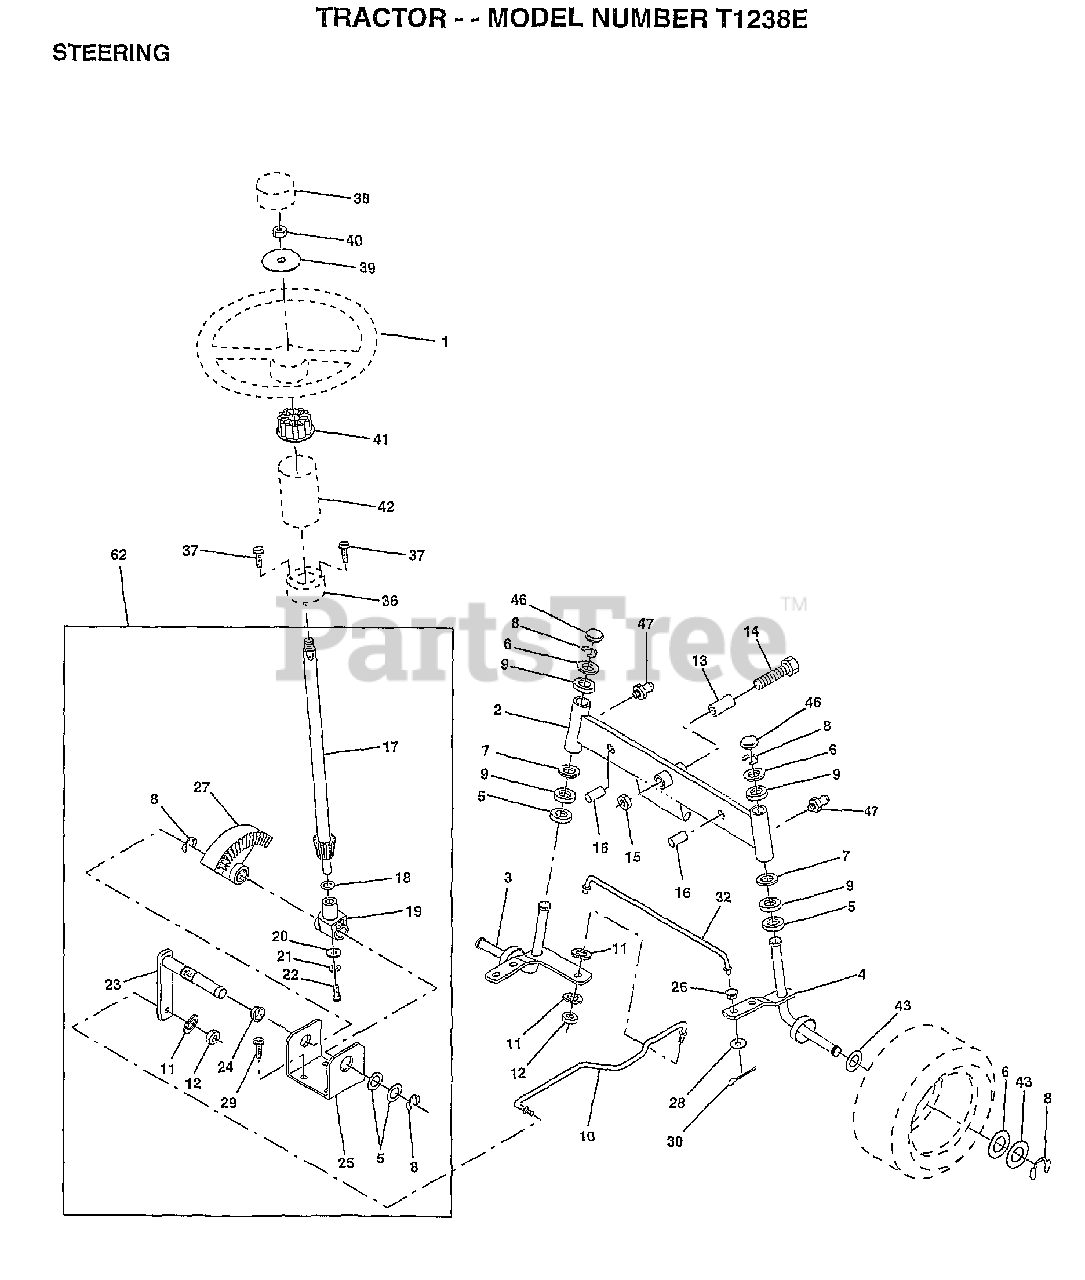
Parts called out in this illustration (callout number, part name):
2	AXLE ASM FRONT
3	SPINDLE LH
4	SPINDLE RH
5	WASHER .T
6	WASHER
7	WASHER
8	RING
9	COL. SRTG. BEAR.
11	LOCKWASHER
13	BEARING
14	BOLT HEX 5/8-11
15	"NUT-LOC,FLANGE LT"
16	AXLE PIN
17	SHAFT ASM
18	THRUST WASHER
19	SUPPORT.SHAFT
21	LOCKWASHER
22	SCREW.SCKTHD.CAP
24	NYLINER T
25	"BRKT,STEERING"
26	BUSHING.DRAGLINK
27	GEAR SECTOR
28	WASHER
29	SCREW
30	COTTER PIN
32	TIE ROD
37	"SCREW-TT,10-32 FL"
38	ST WHL INSERT CAP
39	WASHER T
40	GRIPCO NUT
41	ADAPTER-WHEEL LT
42	"TUBE, STR SHAFT"
46	CAP
47	ZERK M
